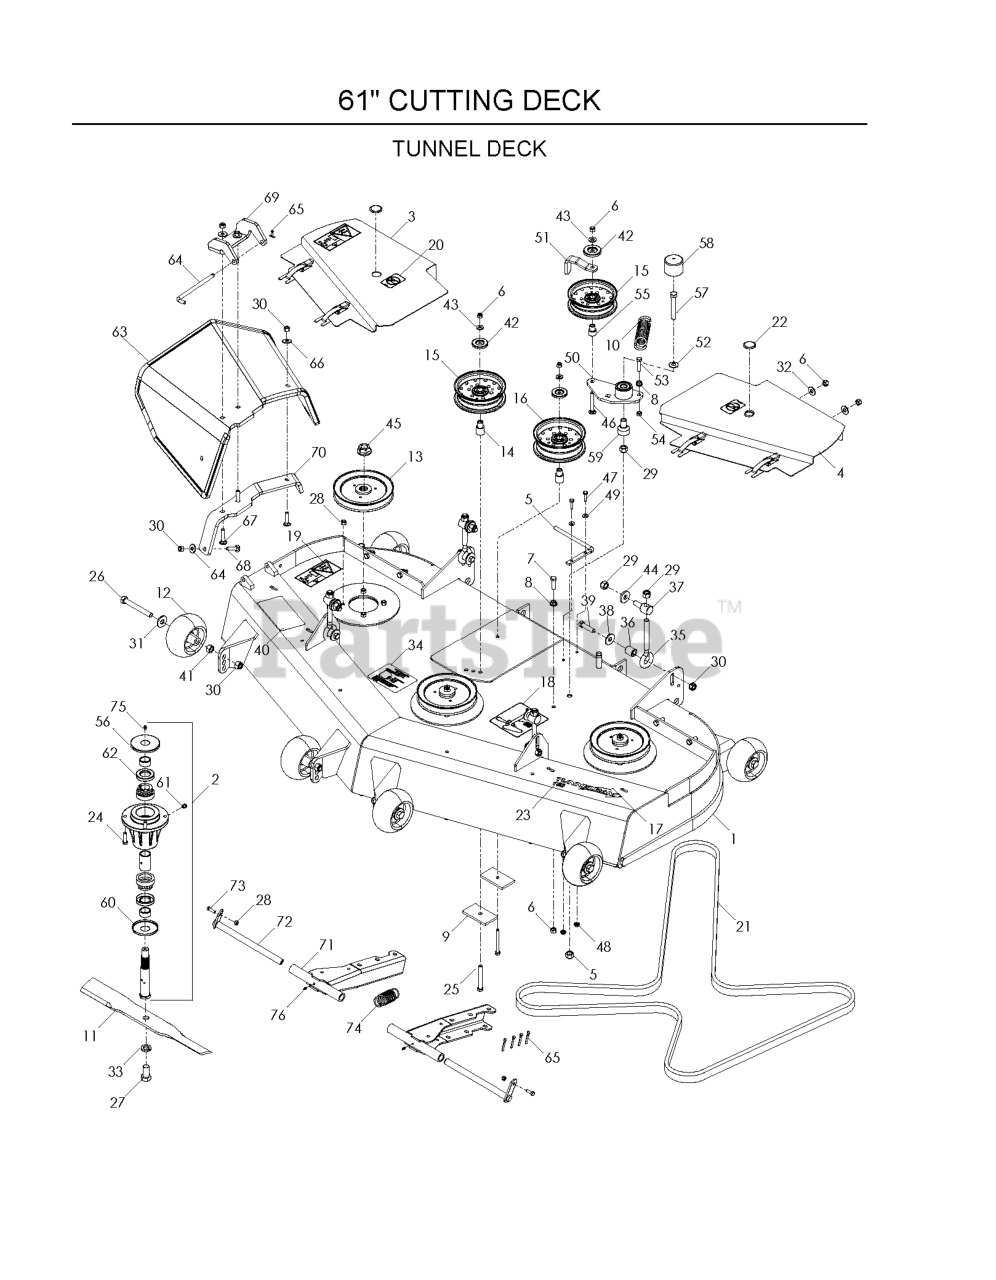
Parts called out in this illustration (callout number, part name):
1	DECK W/DECALS 61" HUS
2	HOUSING ASM, 52/61
3	BELT SHIELD RH 61 EU
4	BELT SHIELD LH EU 61
5	BELT GUIDE
6	NUT 3/8-16 NYLOC
7	HCS 3/8C X 1 1/4 GR5
8	NUT 3/8C WHIZ
9	SUPPORT PLATE
10	DECK SPRING
11	BLADE, 21"
12	GAUGE WHEEL
13	PULLEY, 61
14	IDLER BUSHING
15	IDLER PULLEY
16	PULLEY - IDLER, 6IN WIDE
17	DECAL, TUNNEL RAM 8"
18	DECAL, BELT ROUTING
19	DECAL, EURO SEVERING
20	DECAL, NO STEP
21	BELT, DECK 61
22	BUTTON PLUG - 1" NOM.
23	DECAL, 155
24	HCS 5/16C X 1 1/4
25	HCS 3/8C X 3
26	HCS 1/2-13 X 4 GR 5 ZD
27	HCS 5/8F X 1 1/4
28	NUT 5/16 NYLOC
29	NUT 1/2-13 HEX NYLOC ZD
30	NUT 7/16C CENTERLOCK
31	WASH USS FLAT 1/2
32	WASHER 3/8 FLAT
33	LOCKWASHER 5/8
34	DECAL, ANTI SCALP
37	SWIVEL, DECK HEIGHT ADJ
38	SPRING WASHER - .50
39	HCS 7/16 - 14 X 1 3/4
40	DECAL, DISCHARGE, MULTILINGUAL
41	NUT HEX 1/2
42	DUST SHIELD
43	WASHER, 3/8 THICK
45	NUT FLANGE 3/4-16
46	RHSNB 3/8-16 X 2.75
47	HCS 1/4 X 1
48	NUT 1/4-20 HEX FLG LK ZD
49	WASHER 1/4 SAE
50	ARM-IDLER W/BRG
51	GUIDE, BELT
52	CONTACT BELLSPR 1/2
53	HCS 3/8-16 X 1-1/2
54	NUT 3/8-16 HEX JAM
55	BUSHING, IDLER
56	TOP DUST CAP
57	HCS 1/2C X 3 1/4
58	CAP, VINYL
59	PIVOT, BEARING
60	BOTTOM DUST CAP
61	PLUG-VENTED
62	SHAFT SEAL
63	CHUTE, RUBBER DISCHARGE 52/61"
64	PIN, CHUTE PIVOT
65	RP_COTTER PIN 1/8 X 3/4
66	WASHER 5/16 FLAT
67	BOLT, CARRIAGE 5/16X1-1/4
68	RHSNB 5/16-18 X 1-1/2 GR 5 ZD
69	PIVOT BRACKET - RUBBER CHUTE
70	BRACKET, REINF-CHUTE
71	STRUT WELDMENT, TRD
73	HCS 5/16C X 1
74	DECK LIFT SPRING
76	ZERK
